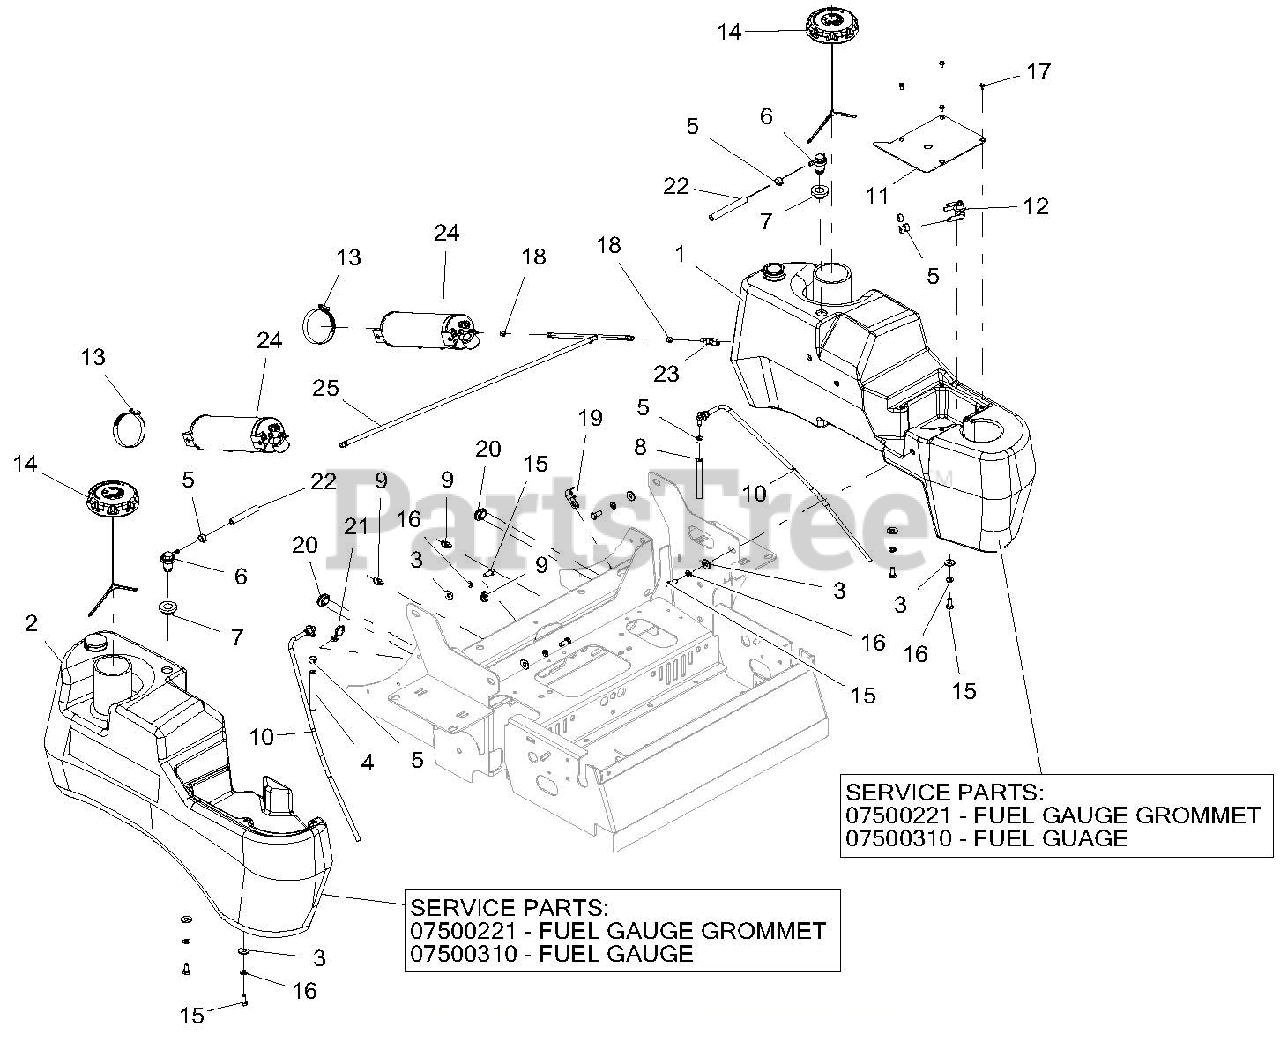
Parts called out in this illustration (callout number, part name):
1	ASSY-LH LARGE FUEL TANK W/MECH GAUGE-GAS
1	FUEL GUAGE GROMMET
1	FUEL GUAGE
2	ASSY-RH LARGE FUEL TANK W/MECH GAUGE-GAS
2	FUEL GUAGE GROMMET
2	FUEL GUAGE
3	WSHR-FL-STL.38X.875X.083 YWZC
4	.25 LOW-PERM GAS HOSE 54.00" LG - RH TANK TO VALVE
5	CLAMP, FUEL LINE
6	VALVE, COMBINATION
7	GROMMET, REMOTE VENT NITRILE
8	.25 LOW-PERM GAS HOSE 19.00" LG - LH TANK TO VALVE
9	CLIP, ROUTING
10	ASM, LARGE TANK FUEL PICKUP
11	PLATE, FUEL VALVE MOUNTING-RED
12	VALVE, FUEL
13	CLAMP, HOSE 2.3/3.2
14	CAP, NON NONVENT AUTOLOCK
15	BLT-HEX .31-18X.75 GR5 YWZC
16	WSHR-LK .31X.078 REG YWZC
17	SCR-MCH 10-24X.38 HWHSTAINLESS
18	CLAMP - HOSE, SPRING .188
19	CLAMP, CUSHIONED STEEL .75
20	GROMMET, RUBBER
21	CABLE TIE W/ TREE
22	.25 LOW-PERM GAS HOSE 14.00" LG - Tank vent to CARB canister
23	CLIP, T, .38-.50
24	CANISTER, CARBON 9.3 GAL
25	PT200-400 KAW CARB FUEL LINE ASSEMBLY
